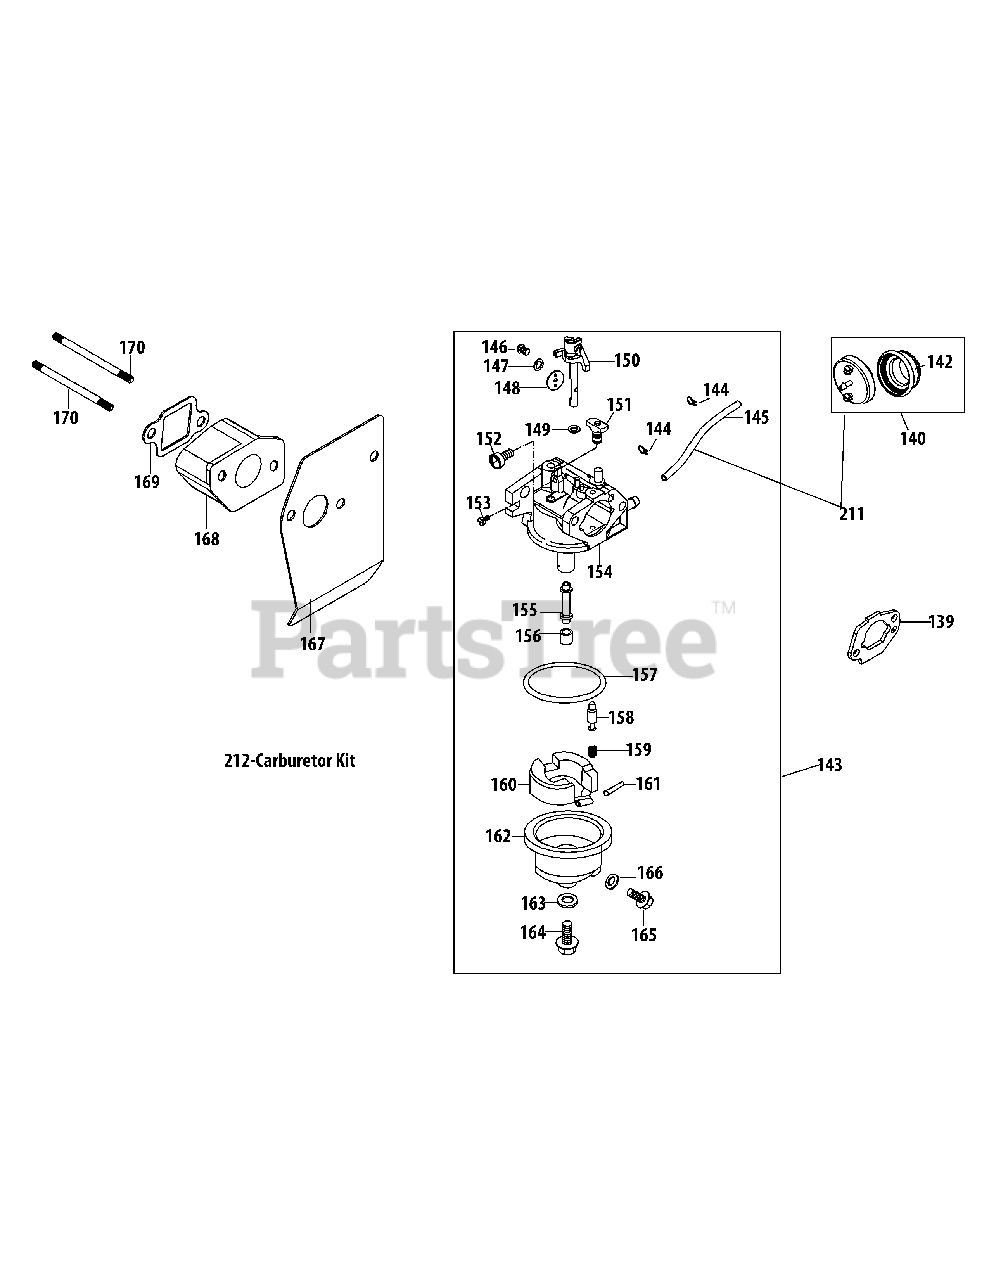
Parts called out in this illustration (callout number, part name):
139	Carburetor Gasket Plate
140	Primer Assembly
142	Primer Bulb
143	Carburetor Assembly
144	Primer Hose Clamp
145	Primer Hose
146	Screw M3X6 Throttle Plate
147	Throttle Plate Lock Washer
148	Throttle Plate
149	Throttle Shaft Fiber O-Ring
150	Throttle Shaft
151	Idle Jet Assembly
152	Idle Speed Adjusting Screw
153	Idle Mixture Screw
154	Carburetor Body
155	Emulsion Tube
156	Main Jet
157	Fuel Bowl O-Ring
158	Needle Valve
159	Needle Valve Spring
160	Float
161	Float Pin
162	Fuel Bowl
163	Fuel Bowl Gasket
164	Fuel Bowl Mounting Bolt
165	Fuel Drain Plug
166	Fuel Drain Plug Gasket
167	Carburetor Gasket
168	Carburetor Insulator
169	Carburetor Insulator Gasket
170	Carb Stud M6X113
211	Primer Assembly
212	Carburetor Kit - Major
